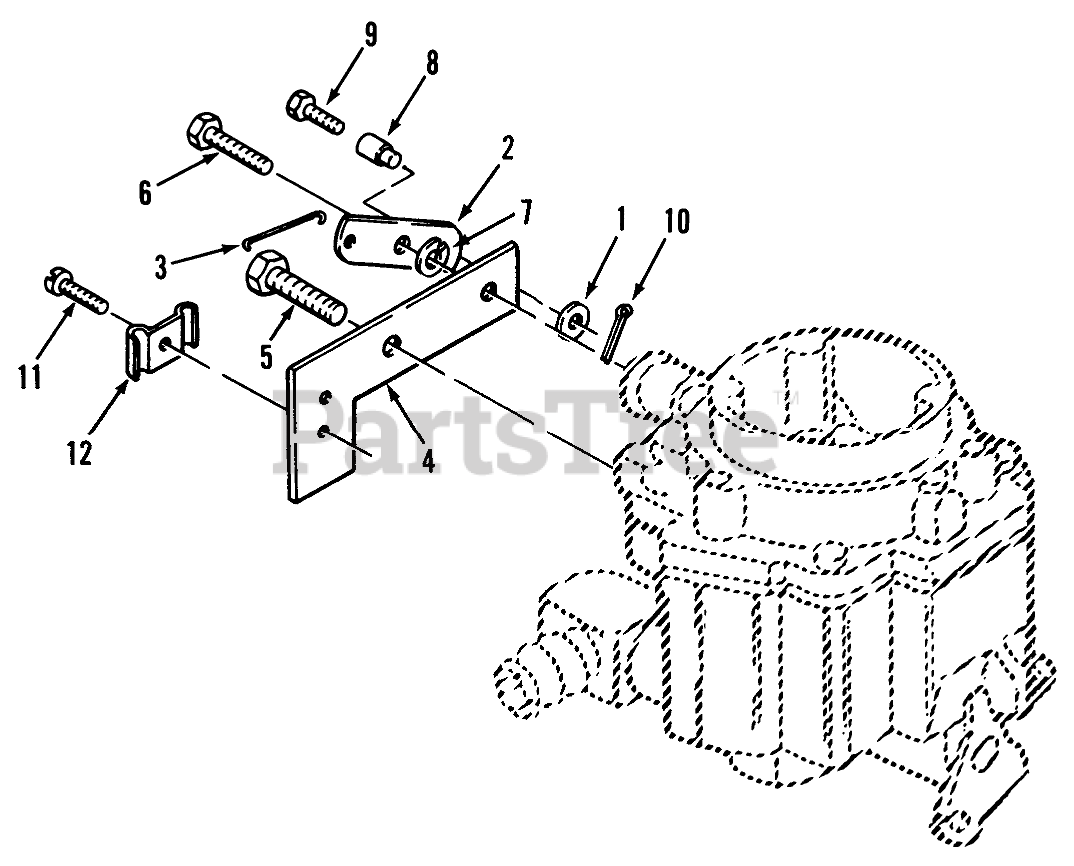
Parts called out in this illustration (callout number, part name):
1	Washer
2	Lever
3	Link
4	Bracket
5	Bolt
6	Bolt
7	Lockwasher
8	Swivel
9	Bolt
10	Cotler Pin
11	Bolt
12	Clip
